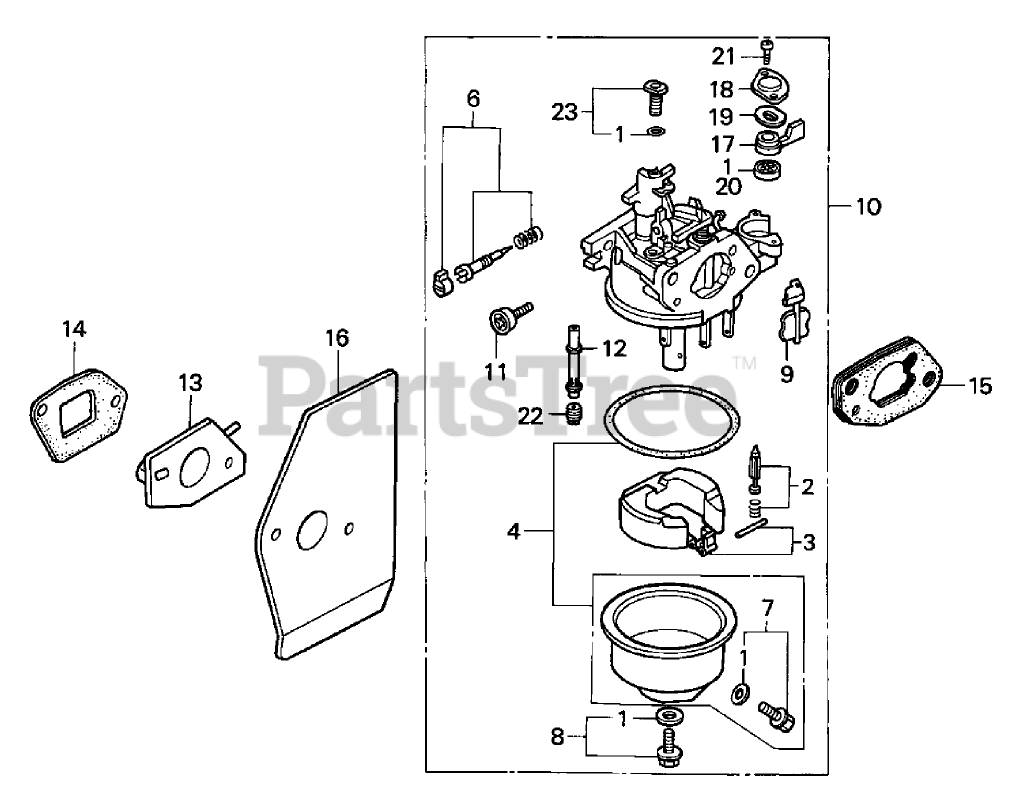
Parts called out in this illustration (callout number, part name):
1	GASKET SET
2	FLOAT VALVE SET
3	Float Set
4	FLOAT CHAMBER SET
6	PILOT SCREW SET
7	DRAIN SCREW SET
8	SCREW SET
9	Choke Set
10	CARBURETOR ASM
11	SCREW- STOP, THROTTLE
12	Nozzle-Main
13	Insulator-Carburetor
14	Gasket-Insulator
15	Spacer-Carburetor
16	Gasket-Carburetor
17	LEVER-VALVE
18	Plate-Lever, Setting(engine serial number up to BE66C A)
19	SPRING-LEVER, PETCOCK
20	GASKET-PETCOCK
21	Screw-Pan (3X6)(engine serial number from BE66C B)
22	JET-MAIN (No. 60)
23	PILOT JET SET (No. 35)
